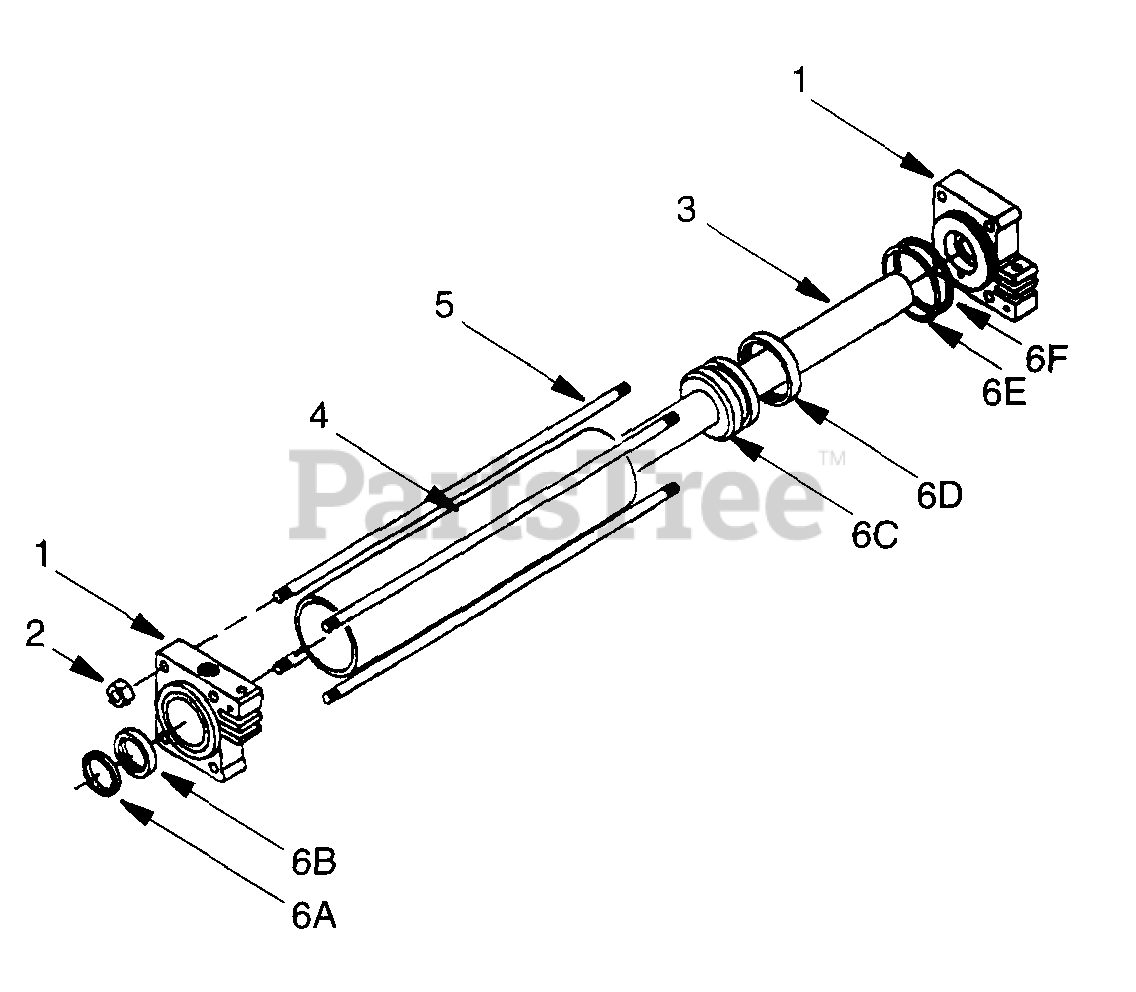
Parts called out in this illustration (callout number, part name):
1	Guide, 2.5 OD x 1.25 ID
2	Hex Nut, 7/16 NC
3	Piston Rod Assy, 1.25 x 2.5
4	Cyl Tube,
5	Tie Rod, .385 Dia x 16
6A	Rod Wiper, 1.25 ID x 1.5 OD
